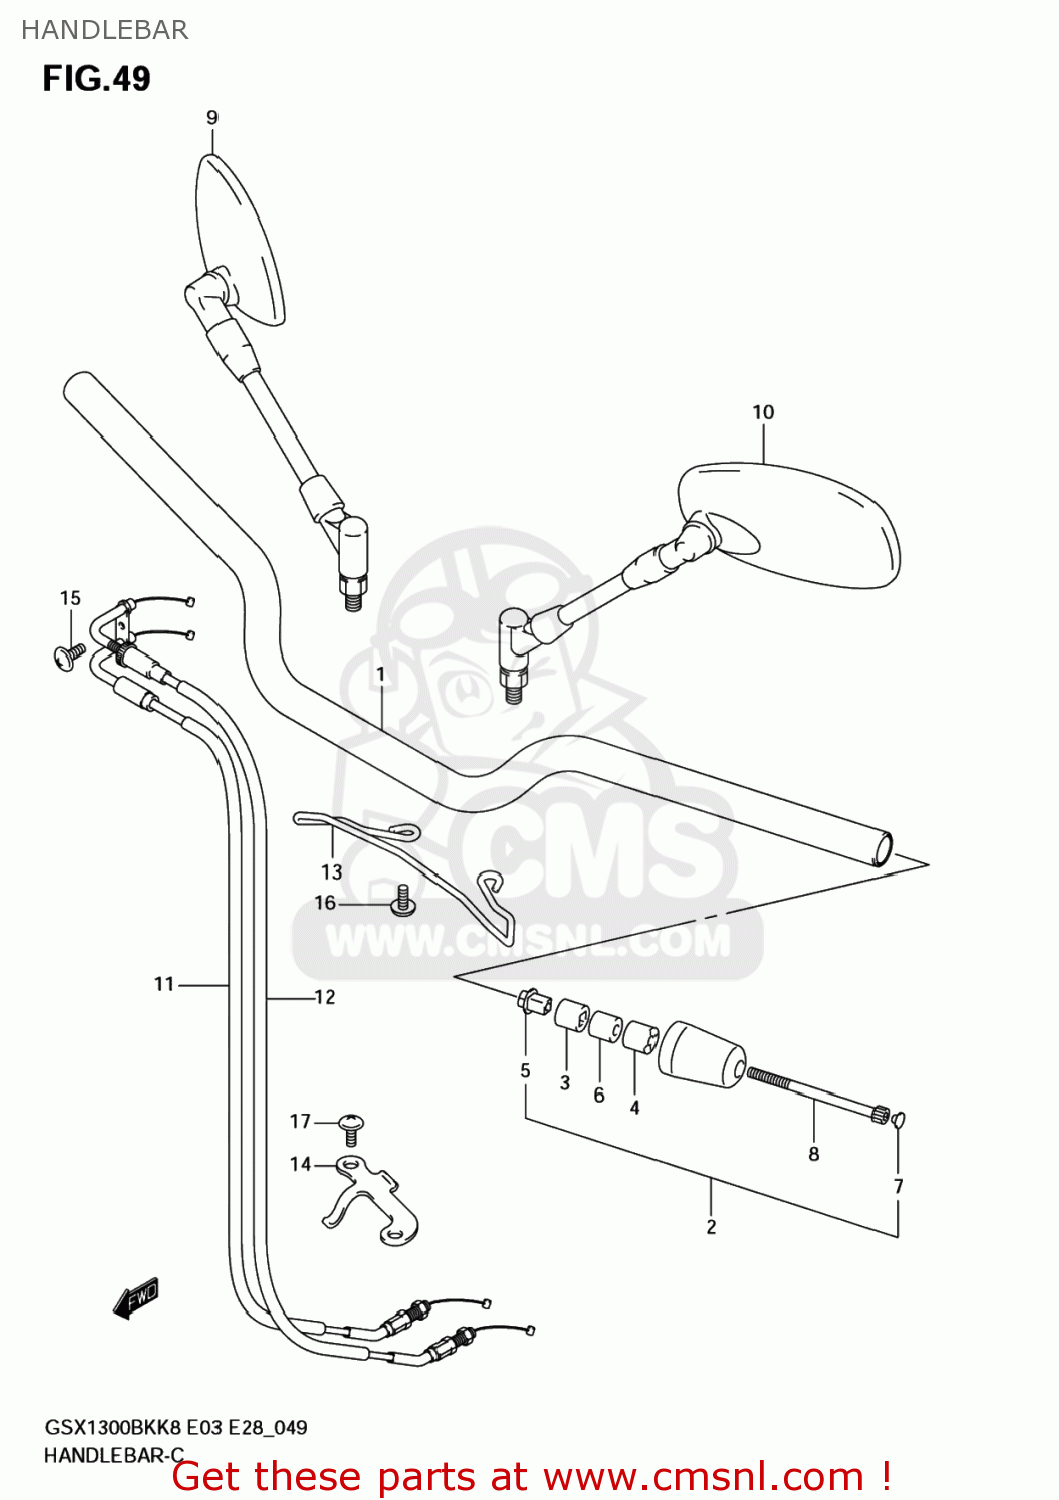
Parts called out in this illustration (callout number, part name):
1	HANDLEBAR
2	BALANCER SET,HANDLEBAR
3	EXPANDER,HANDLE BALANCER
4	EXPANDER,HANDLE BALANCER
5	NUT,HANDLE BALANCER
6	SPACER(6.5X16X15)
7	CAP(OD:10)
8	BOLT
9	MIRROR ASSY,RR VIEW
10	MIRROR ASSY,RR VIEW,L
11	CABLE ASSY,THROTTLE NO.1
12	CABLE ASSY,THROTTLE NO.2
13	GUIDE,CABLE
14	GUIDE,THROTTLE CABLE
15	SCREW(5X10)
16	SCREW(6X16)
17	SCREW
